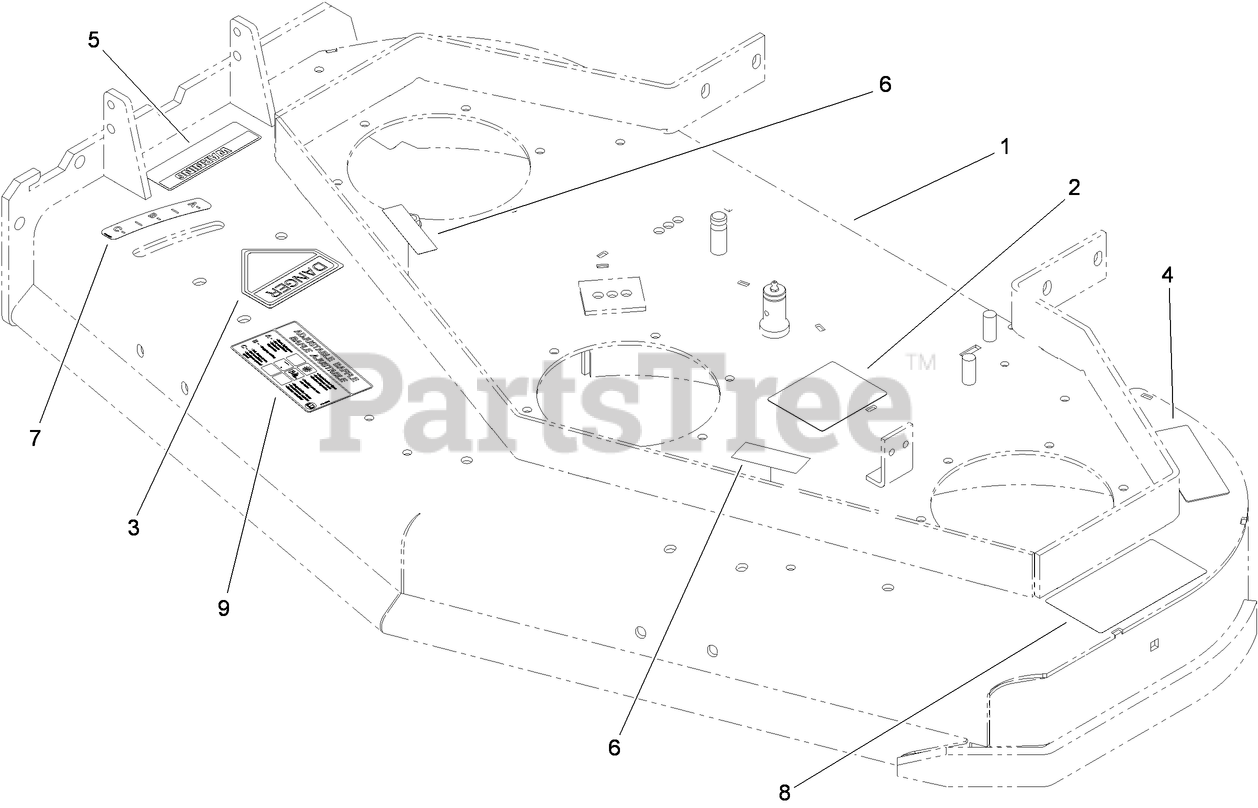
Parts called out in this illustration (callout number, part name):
1	48 INCH DECK ASM
2	DECAL-ROUTING, BELT
3	DECAL-DANGER
4	DECAL-TORQUE, BOLT
5	DECAL-WARNING
6	DECAL-COVER, MISSING
7	DECAL-SETTING, BAFFLE
8	DECAL-DANGER, THROWN OBJECT
9	DECAL-ADJUSTMENT, BAFFLE
